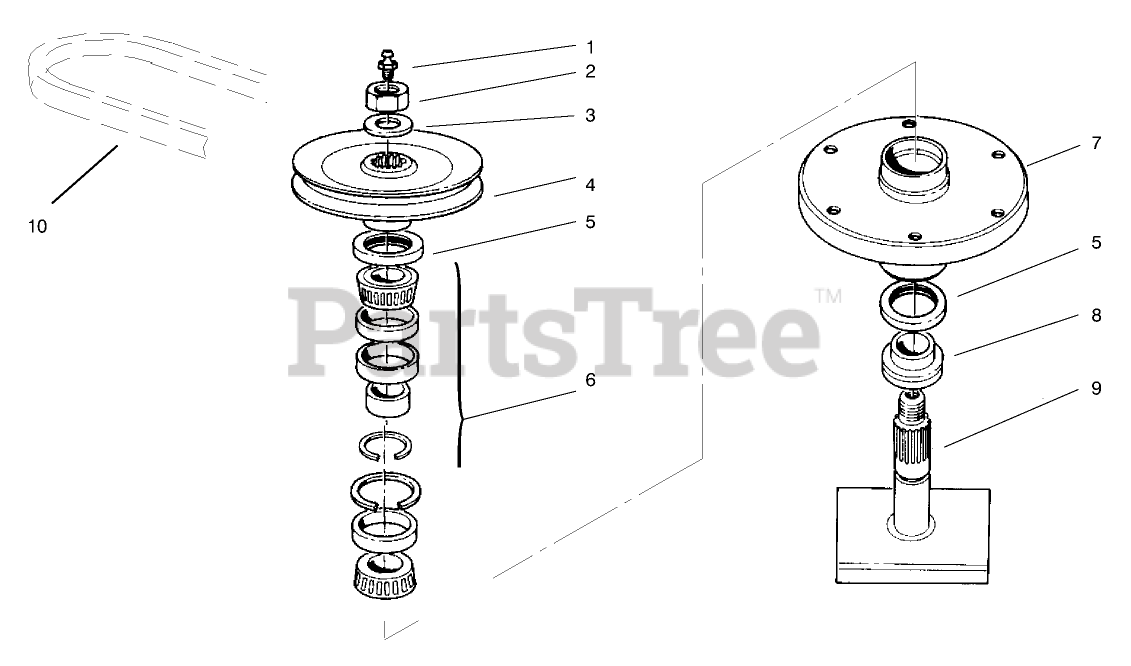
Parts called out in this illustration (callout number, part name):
1	FITTING-GREASE
2	NUT-HEX
3	WASHER
4	PULLEY AND HUB ASM
5	SEAL-OIL
6	BEARING ASM
7	HOUSING-SPINDLE
8	SPACER
9	SHAFT
10	V-BELT-DRIVE, DECK
